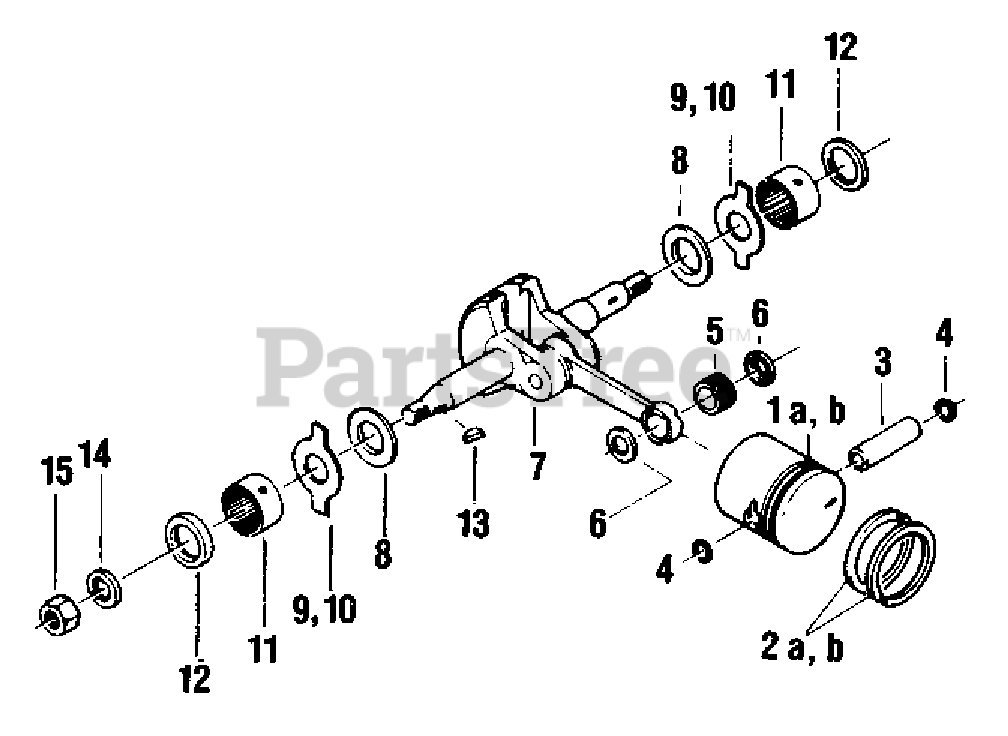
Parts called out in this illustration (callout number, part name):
1A	PISTON
1B	PISTON
2A	RING, PISTON
2B	RING, PISTON
3	PIN, PISTON
4	RING, SNAP
5	BEARING, BALL
6	WASHER, THRUST
7A	CRANKSHAFT ASSY
7B	CRANKSHAFT ASSY
8	WASHER, THRUST
9	PLATE, SIDE - A
10	PLATE, SIDE
11	BEARING, NEEDLE
12	SEAL, OIL
13	KEY, WOODRUFF - 3×10
14	WASHER, SPRING 8
15	NUT
